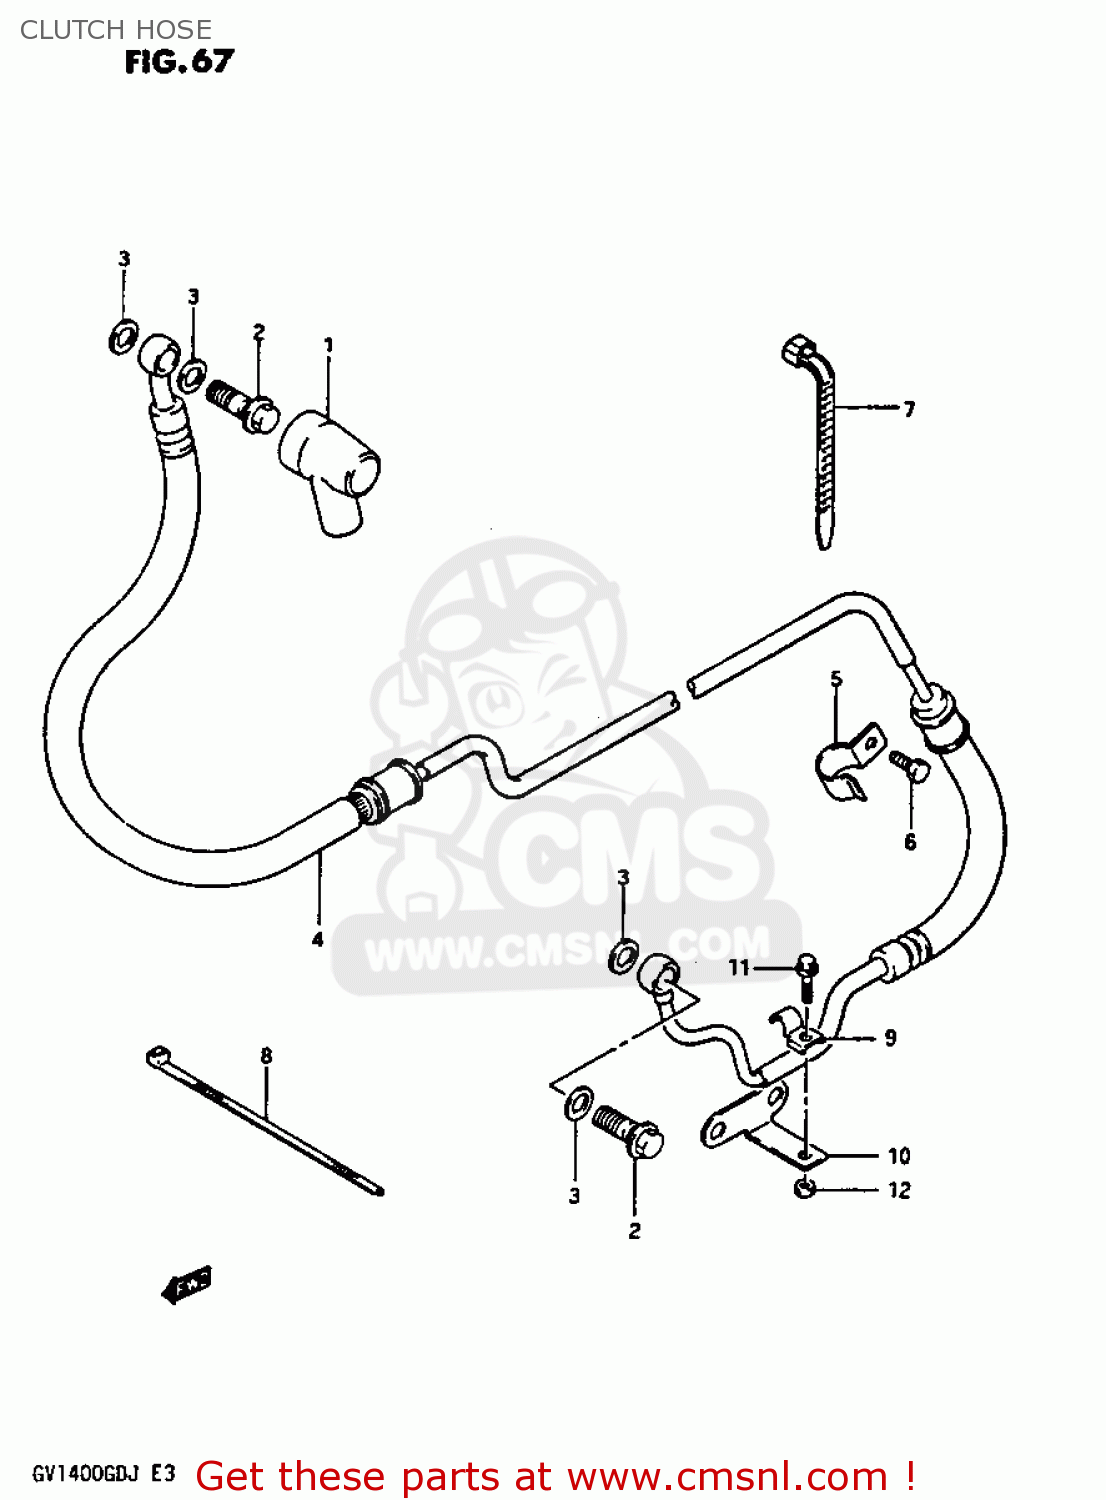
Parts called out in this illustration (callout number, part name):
1	BOOT,MASTER CYLINDER
2	BOLT UNION
3	WASHER(10X15X1.5)
4	HOSE,CLUTCH
5	GUIDE
6	BOLT
7	CLAMP(L:165)
8	CLAMP(L:250)
9	CLAMP, CLUTCH HOSE/GEAR CASE
10	CLAMP,CLUTCH HOSE
11	BOLT 6X12
12	NUT
